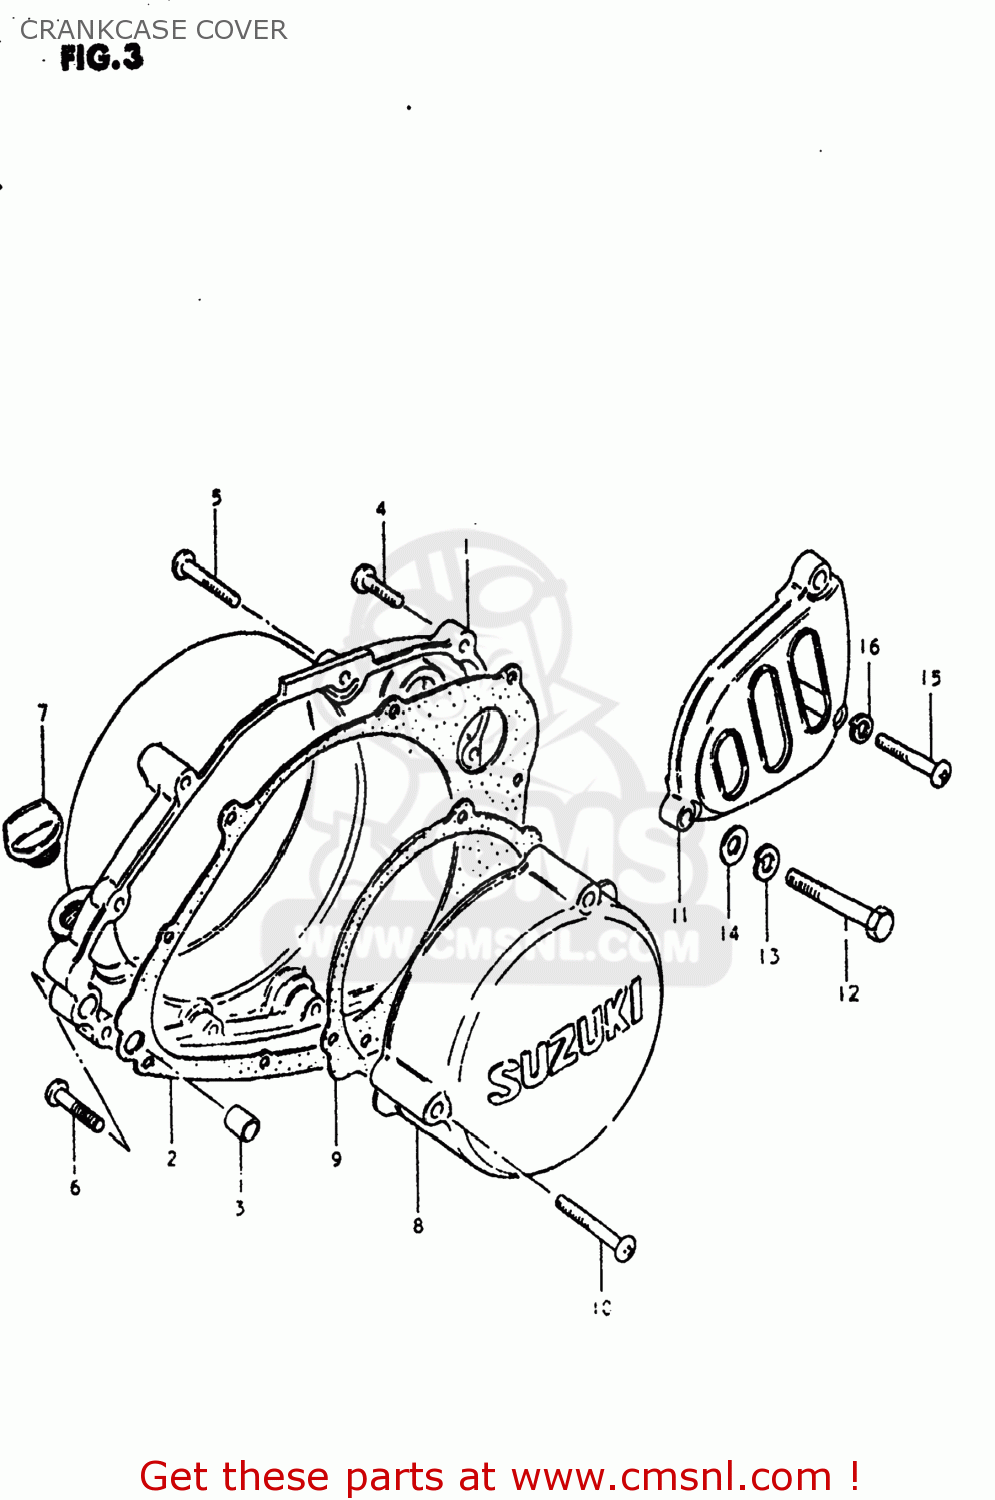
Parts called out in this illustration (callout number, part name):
1	COVER,CLUTCH
2	GASKET,CLUTCH COVER (MCA)
3	PIN
4	SCREW
5	SCREW 6X30
6	SCREW (6X45)
7	PLUG,OIL FILTER
8	COVER,MAGNETO
9	GASKET,MAGNETO COVER (NAS)
10	SCREW
11	COVER,ENGINE SPROCKET
12	BOLT 8X55
13	LOCK WASHER
14	WASHER
15	SCREW
16	LOCK WASHER
